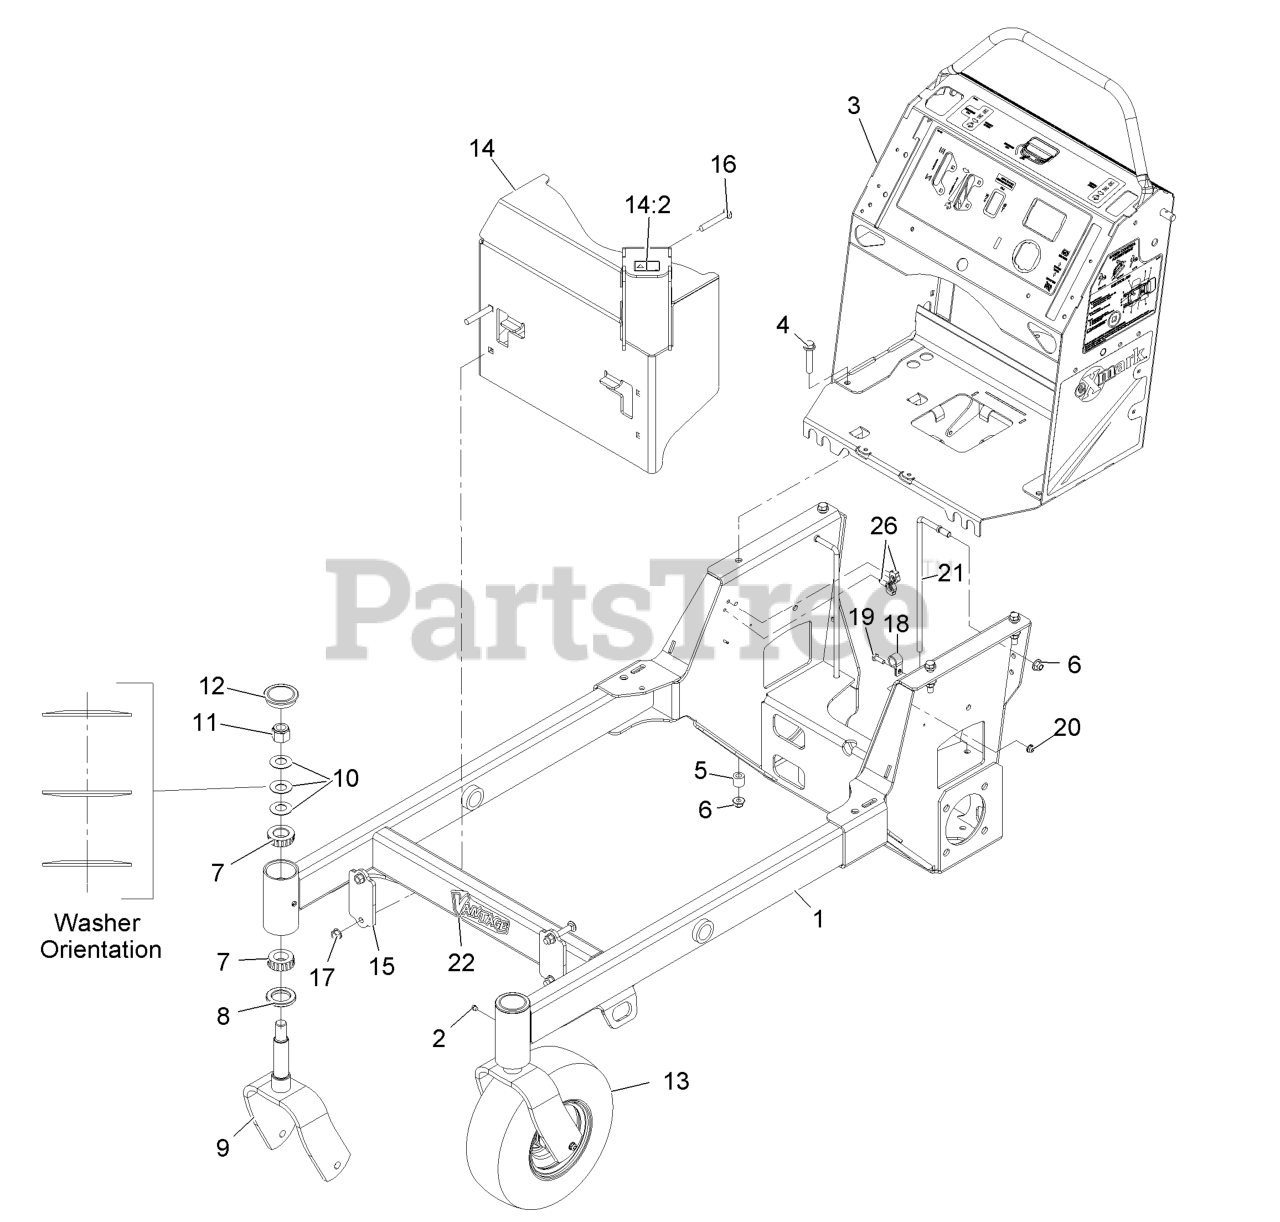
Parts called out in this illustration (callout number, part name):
1	FRAME ASM
3	CONTROL TOWER ASM
4	SCREW-HHF
6	NUT-HF, NI
7	Cone-Bearing Tapered Roller
8	SEAL-GREASE
9	FORK-CASTER
10	WASHER-BELLVILLE
11	NUT-LOCK, NI
12	CAP-GREASE
13	WHEEL/TIRE AND BEARING AS
14:2	DECAL-WARNING
15	BRACKET-MOUNTING, GUARD
16	SCREW-CARR
18	CLAMP-CABLE
19	SCREW-HH
21	GUIDE-HOSE
22	DECAL-VANTAGE LOGO
26	CLIP-HARNESS
